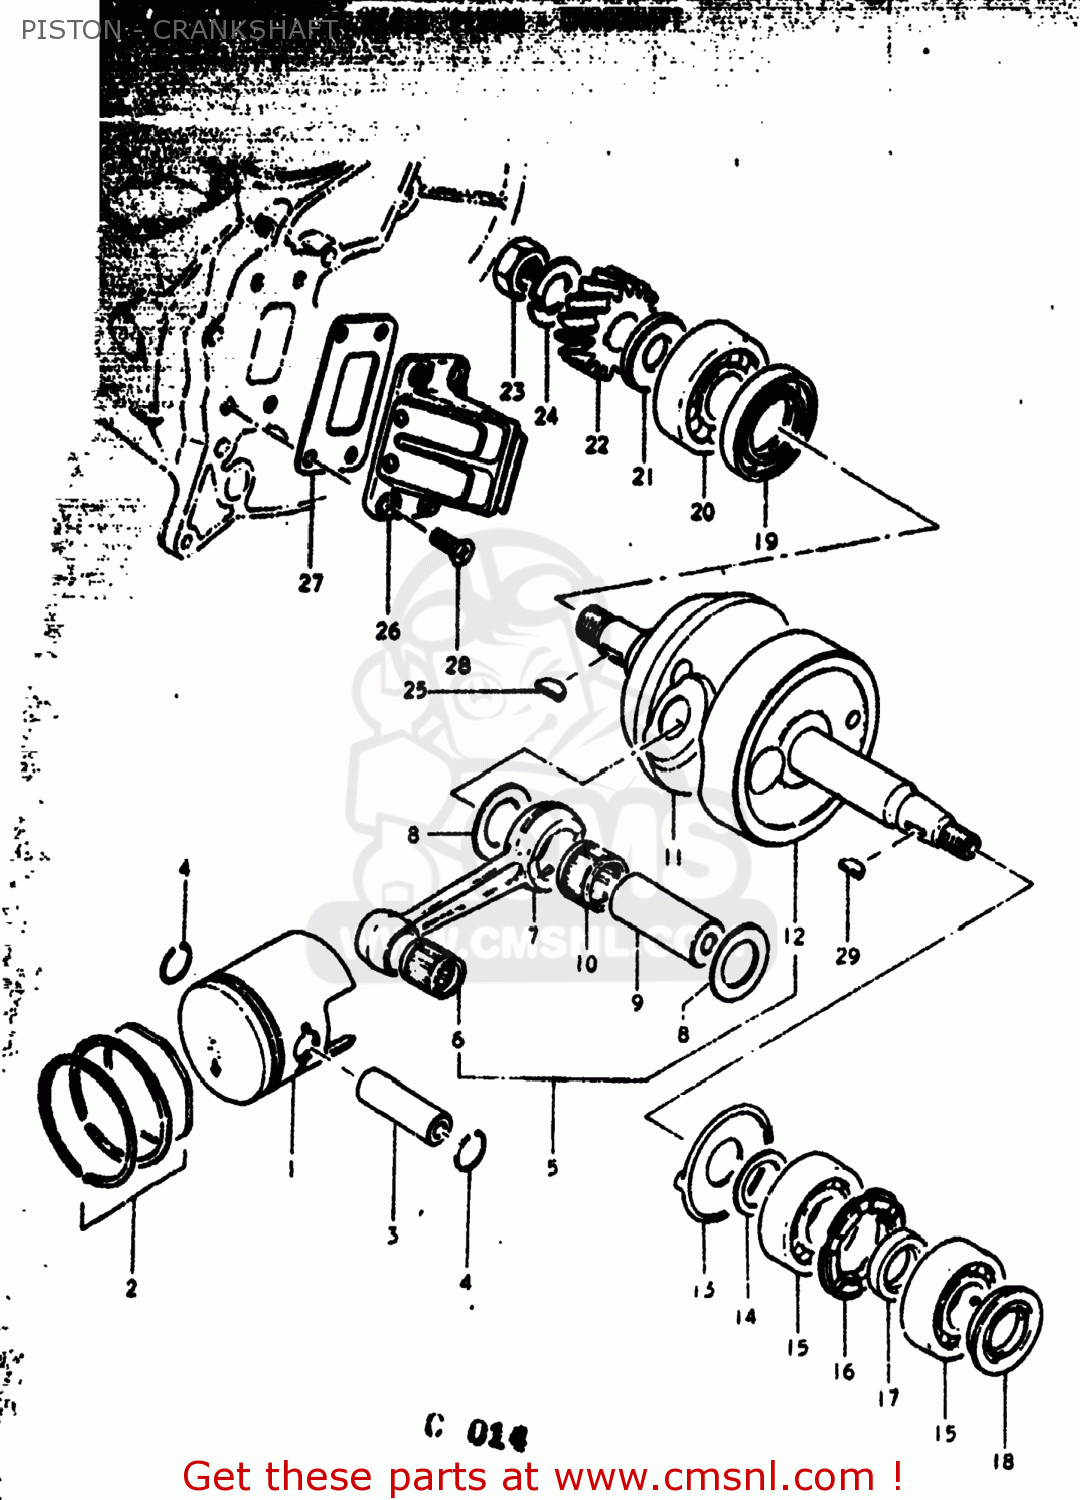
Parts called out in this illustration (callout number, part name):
1	PISTON
2	RING SET,PISTON
3	PIN,PISTON 14MM
4	RING,SNAP 14MM
5	CRANKSHAFT SET
6	BEARING
7	ROD,CONNECTING
8	WASHER
9	PIN,CRANK
10	BEARING
11	CRANKSHAFT, RH K,L,M,A,B
12	CRANKSHAFT,LEFT
13	PLATE,CSHAFT OIL GUIDE
14	THRUST WASHER
15	BEARING
16	SPACER,CRANKSHAFT NO.1
17	SPACER(20X28X7)
18	OIL SEAL
19	SEAL,OIL(26X52X8)
20	BEARING
21	SPACER(16X29.5X4.5)
22	GEAR,PRIMARY DRIVE
23	NUT
24	WASHER
25	KEY 4MM
26	VALVE ASSEMBLY,REED
27	GASKET,REED VALVE (MCA)
28	SCREW
29	KEY
